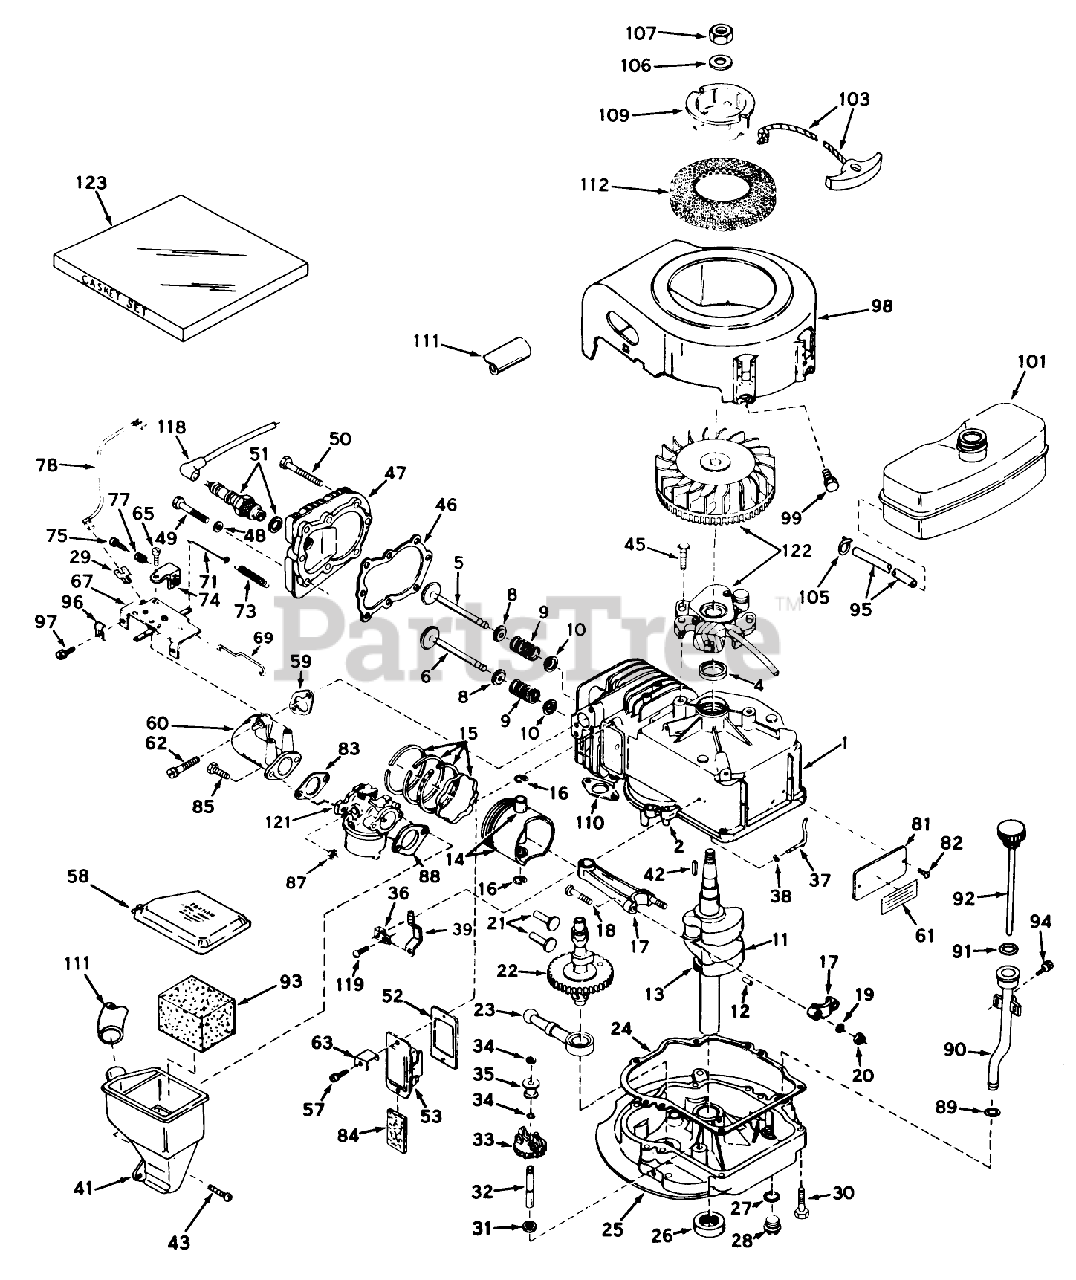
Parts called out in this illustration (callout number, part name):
1	Cylinder Assy. (Incl. Ref. 2 4)
2	Pin-Dowel
4	OIL SEAL
5	Valve, Intake (Incl. Ref. #38, 39 40) (Std.)
5	Valve, Intake(1/32"overs.)(Incl. Ref. 8, 9 10)
6	Valve, Exhaust (Standard)(Incl. Ref. 8, 9 10)
6	Valve, Exhaust (1/32" Overs.(Incl. Ref. 8, 9 10)
8	Cap-Upper Valve Spring
9	Spring-Valve
10	Cap-Valve, Spring
11	Crankshaft Assy. (Incl. Ref. 12 13)(Model LAV35-40455H)
12	Pin, Groove
13	Gear, Crankshaft
14	Piston Pin Assy. (Standard)(Incl. 2 of No. 16)
14	Piston Pin Assy. (.010 overs.)(Incl. 2 of Ref. 16)
14	Piston Pin Assy. (.020 overs.)(Incl. 2 of Ref. 16)
15	Ring Set, Piston (Std.)
15	Ring Set, Piston (.010 o.s.)
15	Ring Set, Piston (.020 o.s.)
16	Ring-Retaining, Piston Pin
17	Rod Assy., Connecting (Incl. Ref. #17)
18	Bolt, Connecting
19	Washer
20	LOCKNUT
21	Lifter-Valve
22	Camshaft
23	Oil Pump ASM
24	Gasket, Mounting
25	Flange Assy., Mounting (Incl. Ref. 26, 27, 28 32)
26	Seal Oil
27	Gasket-Oil Drain
28	Plug Oil Drain
29	Terminal
30	Screw (1/4-20 x 1-1/4)
31	Washer-Flat
32	Shaft-Governor
33	Governor Gear ASM
34	Ring-Retaining
35	Spool-Governor
36	Clamp-Lever, Governor
37	Rod, Governor (Incl. No. 36)
38	Washer-Flat
39	Governor Lever
41	Body, Air Cleaner
42	Key Flywheel
43	Screw, Fil. Hd. Sems
45	Screw
46	Gasket-Cylinder Head
47	CYLINDER HEAD
48	Washer
49	Screw
50	Screw Hex Hd. Cap
51	SPARK PLUG
52	Gasket Breather
53	Breather Assembly (Incl. Nos. 52 84)
57	Screw
58	Cover, Air Cleaner
59	Gasket, Intake
60	Pipe, Intake
61	480B GIL SNWTHWR O/
62	Screw (1/4-20 x 1)
63	Retainer Clip
65	Screw (10-24 x 9/16)
67	Control Assy., Speed
69	Link Governor
71	Link-Governor
73	Spring, Governor
74	Brachet, Control
75	Screw, Hex Hd.
77	Spring
78	Wire, Ground
81	IDENTIFICATION PLATE
82	Stud
83	Gasket
84	Element-Breather
87	Nut and Lock Washer (1/4-28)
88	Gasket-Air Cleaner
89	O-Ring
90	Tube Assy., Oil Fill
91	O-Ring
92	Dipstick, Oil
93	Element, Air Cleaner
94	Screw (10-32 x 1/2)
95	Line-Fuel (8.62)
96	Conduit
97	Screw (10-32 x 3/8)
98	Housing, Blower
99	Screw (1/4-20x19/32)
101	Tank, Fuel
103	Rope Assy., Starter
105	Clamp-Line, Fuel
106	Washer
107	Hex Nut
109	Pulley Starter
110	Gasket Exhaust
111	Tube, Air Cleaner
112	Screen, Air
118	Cover-Spark Plug
119	Screw
121	Carburetor
122	Magneto
123	Gasket Set
